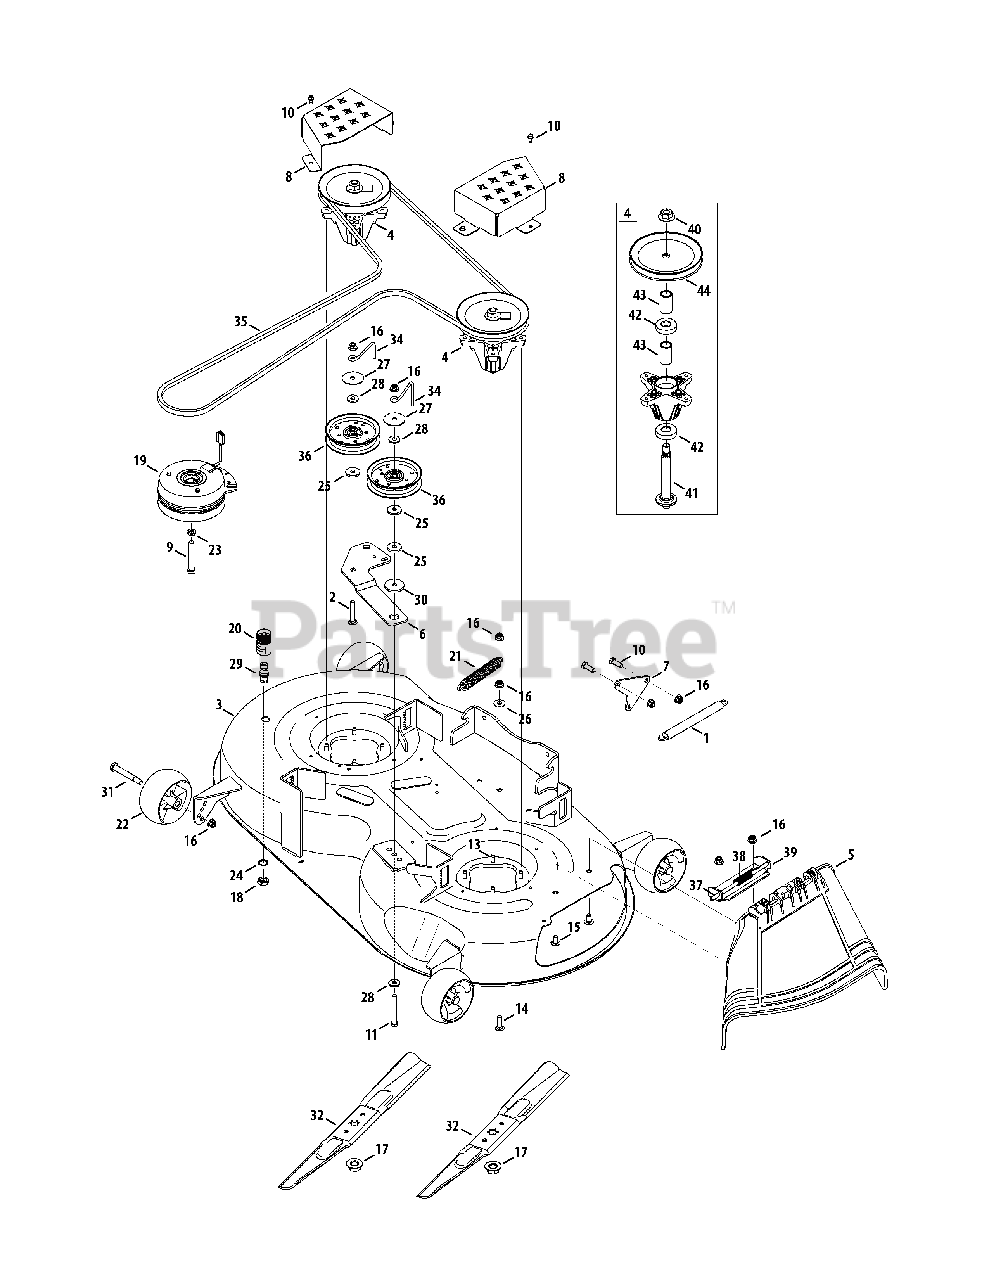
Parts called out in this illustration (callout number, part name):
1	Spring, Extn, Hook, .75x7.89x.14, Bz
2	Carriage Bolt, 3/8-16
3	Deck Assembly, Sd, 46
4	Spindle Assembly, Pulley 6.93 Dia W/O Zerk
5	Chute Deflector Assembly
6	Idler, Plate, 48
7	Plate, Mount, Spring
8	Cover, Belt, Zforces, 46 Deck
9	Screw, 7/16-20, 3.00, Gr5, Std
10	Screw, 3/8-16, 1.00, Gr5, Std
11	Screw, 3/8-16, 3.00, Gr8, Std
13	Screw, Tt, 5/16-18, 1.000, Hxindwsh
14	Bolt, Crg, 3/8-16, 1.25, Gr1
15	Bolt, Crg, 3/8-16, 0.75, Gr1
16	Nut, Flglk, 3/8-16, Grf, Nylon
17	Nut, Flg, 5/8-18
18	Nut, Hex, M16-1.5 Din 936
19	Clutch, Elec, Brake 125 Ft-Lbs
20	Adap, Water Nozzle
21	Spring, Extn, .91 Dia X 7.33
22	Wheel, Deck, 5.0 Dia Ball
23	Washer, Lock, 7/16, SPlate, Reg
24	Washer, Lock, 5/8, Int Tooth
25	Washer, Flat, .406x1.260x.170
26	Washer, Flat, .58 X 1.125 X .08, Ht
27	Washer, Flat, .406x1.920x.060
28	Washer, Flat, .406 X 1.00 X .105
29	Nozzle, Deck, Water
30	Spacer, Shldr, .884 X .190
31	Bolt, Shldr, .496 X 2.50, 3/8-16
32	Blade, Cut, 23.25" 2-In-1
34	Rod, Keepr, Belt 42 Idler
34	Rod, Keepr, Belt 46" Idler
35	Belt, V Typ, A Sec X 122.0
36	Pulley, Idler, 4.25"Dia
38	Torsion Spring
39	Chute Bracket
40	Flange Nut, 5/8-18
41	Spindle Shaft, 6.11 Long
42	Ball Bearing, .787 x 1.85 x .551
43	Spacer, .792 x 1.060 x 1.860
44	Deck Pulley, 6.93 dia.
